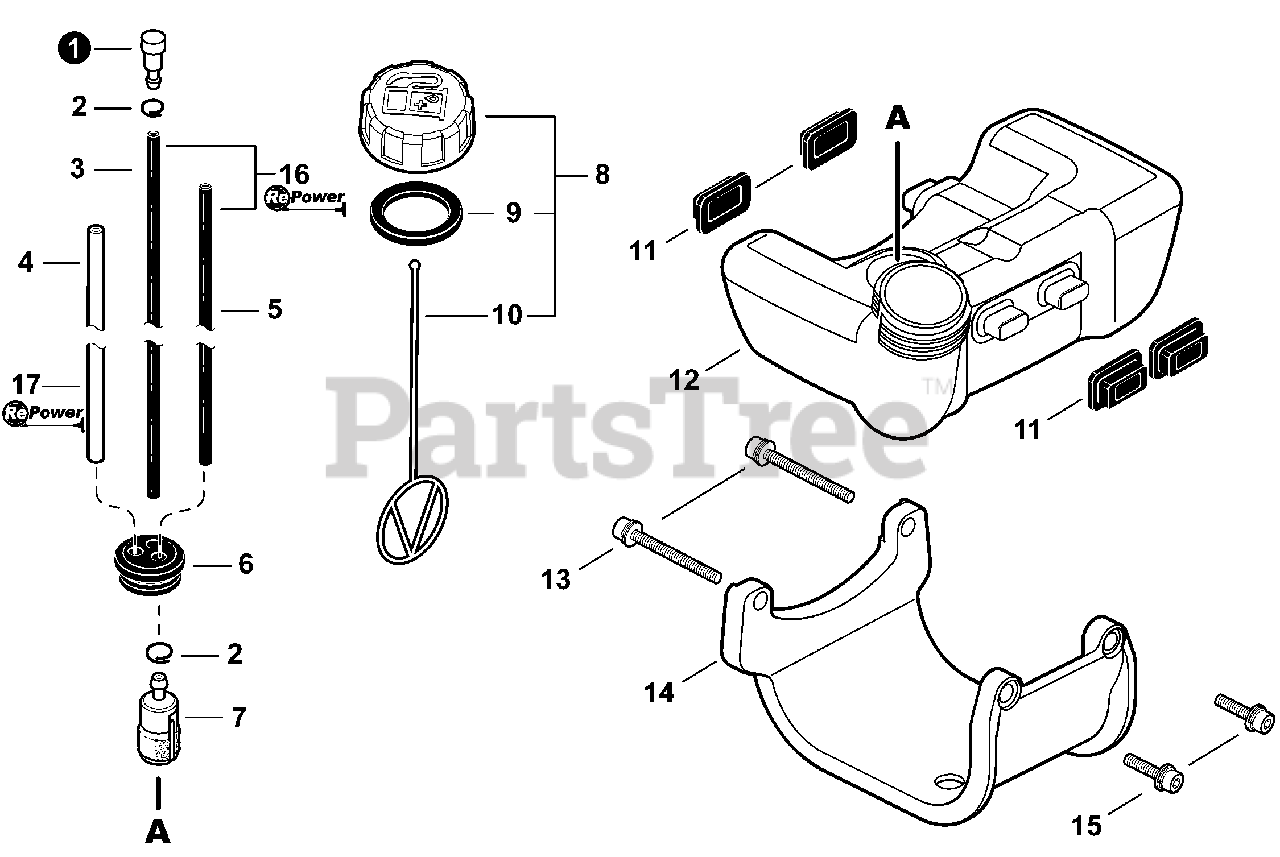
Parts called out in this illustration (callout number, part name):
1	VENT ASSY
2	CLIP 6.5MM
3	PIPE, FUEL 3×6×105 BLACK
4	PIPE, FUEL 3×6×85 CLEAR
5	PIPE, FUEL 3×6×210 BLACK
6	GROMMET, FUEL
7	FILTER, FUEL
8	CAP ASSY, FUEL
9	GASKET, FUEL CAP
10	CONNECTOR, CAP L= 123
11	CUSHION, FUEL TANK
12	TANK, FUEL
13	BOLT 5×40
14	GUARD, FUEL TANK
15	BOLT 5×18
16	PIPE, BULK - 3×6mm BLACK
17	PIPE, BULK - 3×6mm CLEAR
